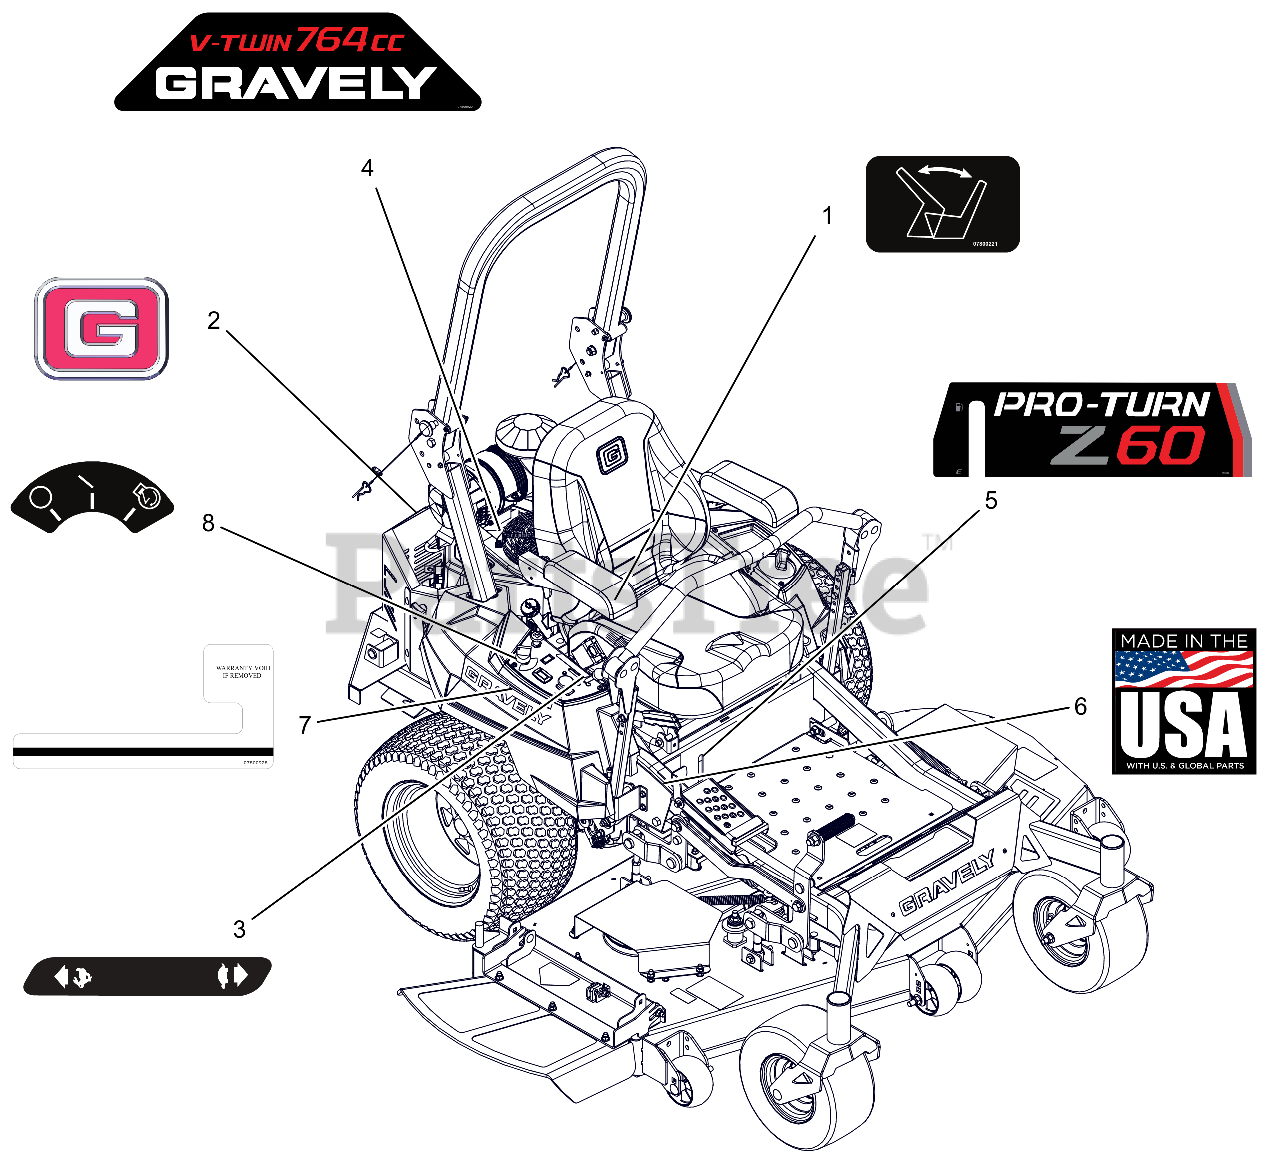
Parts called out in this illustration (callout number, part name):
1	DECAL - SEAT RELEASE
2	DECAL, GRAVELY BRAND
3	DECAL, DASH DECAL
4	DECAL,ENGINE - GRAVELY 764CC
5	DECAL, PRO-TURN Z60
6	DECAL, MADE IN USA
7	DECAL,HOURMETER - SECURITY
8	DECAL, KEYSWITCH
